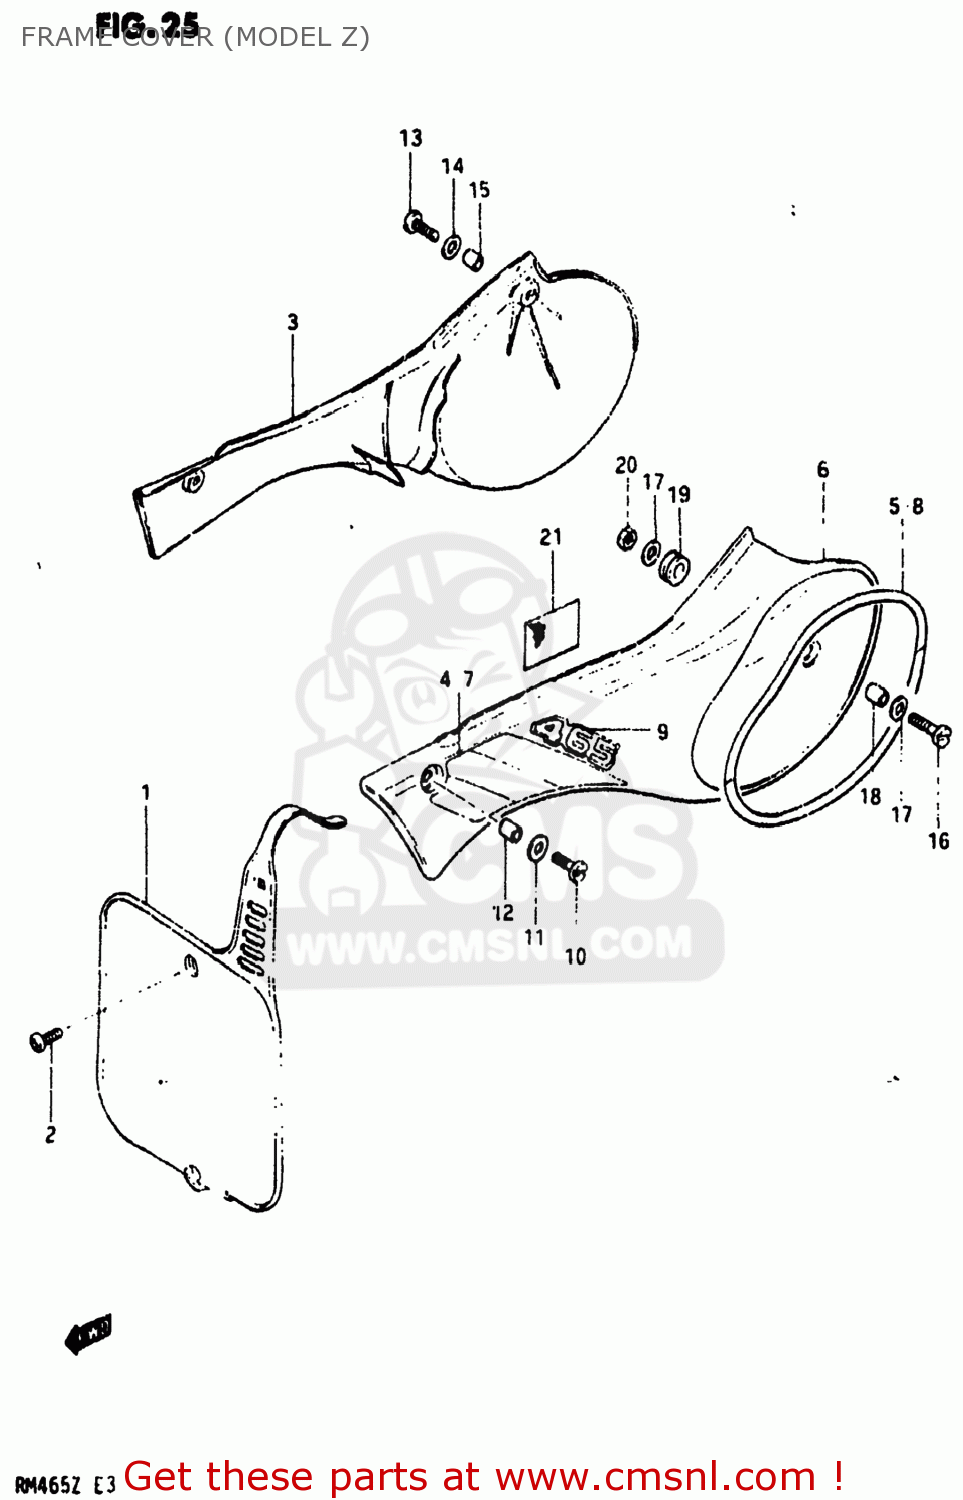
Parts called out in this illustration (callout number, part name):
1	PLATE,NUMBER,FRONT
2	SCREW
3	COVER,FRAME,RIGHT
4	TAPE,FRAME COVER,RIGHT
5	TAPE SET,FRAME COVER
6	COVER,FRAME,LEFT
7	TAPE,FRAME COVER,LEFT
8	TAPE SET,FRAME COVER,RIGHT
9	EMBLEM (465)
10	SCREW(6X25)
11	WASHER FRAME COVER
12	SPACER,FRAME COVER,FRONT
13	SCREW
14	WASHER FRAME COVER
15	SPACER FRAME COV RR
16	SCREW
17	WASHER FRAME COVER
18	SPACER,FRAME COVER,FRONT
19	CUSHION
20	NUT 6MM
21	HEAT SHIELD,FRAME COVER
